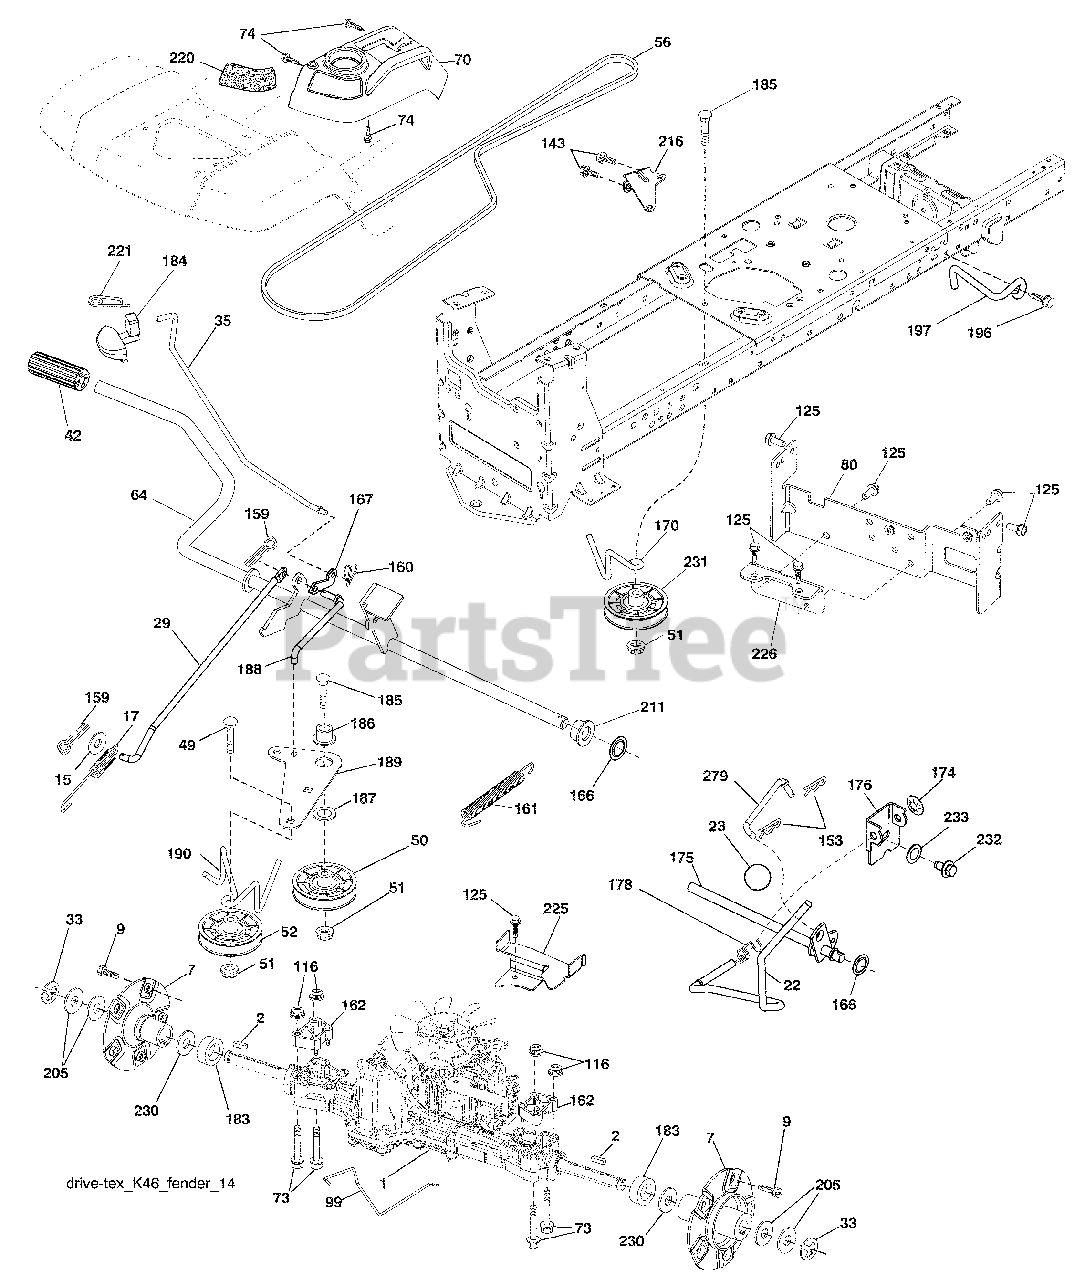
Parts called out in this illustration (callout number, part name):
1	Transaxle, TUFFTORQ K46 AW
7	Hub Asm. Wheel Rear 22" TX GT .06
9	Bolt Hub Wheel Rear
15	Washer 13/32 x 13/16 x 16 Ga.
17	Spring Brake
29	Rod, Brake
35	Rod Brake Park
42	Cover Foot Pedal
50	Pulley Idler Flat
51	Lock Nut 3/8-16
52	Idler V-Groove 910" Offset
56	V-Belt Drive
64	Shaft Asm. Pedal Brake Control
70	Console Asm.
73	Bolt Hex Flghd 5/16-18 x 3.75
74	Screw 1/4 x 1/2
80	Strap Torque
99	Rod Bypass
116	Nut Lock Hex Flange 5/16-18
125	Screw 5/16-18 x 3/4
143	Screw 5/16-18 x 1/2
153	Retainer Spring
159	Pin Cotter 1/8 x 3/4
160	Retainer Clip
161	Spring Return Clutch
162	Spacer Transaxle 18 and 22
166	Nut Push
167	Latch Brake Parking
170	Keeper Belt Centerspan
175	Shaft Asm Shift
176	Arm Clevis Rod Shift
178	Spring Shift
183	Spacer Split
184	Handle Parking Brake
185	Bolt Rdhd Sqnk 3/8-16 x 2-3/4 Gr. 5
186	Spacer Retainer
187	Washer
188	Link Clutch Ground Drive
189	Bellcrank Ground Drive
190	Keeper Bellcrank Ground Drive
196	Screw 3/8-16 x 1
197	Link Clutch Anti-Rotation
211	Bushing Brake Shaft
216	Bracket Pulley Idler
220	Reflector RH
221	Retainer Spring Clip Handle
225	Keeper Belt Trans.
226	Bracket Mount Torque
230	Washer Hardened
231	Idler V-Groove 1.688" Offset
232	Bolt 7/16-14 x 1 Gr. 5
233	Washer Serrated
279	Link Shift
